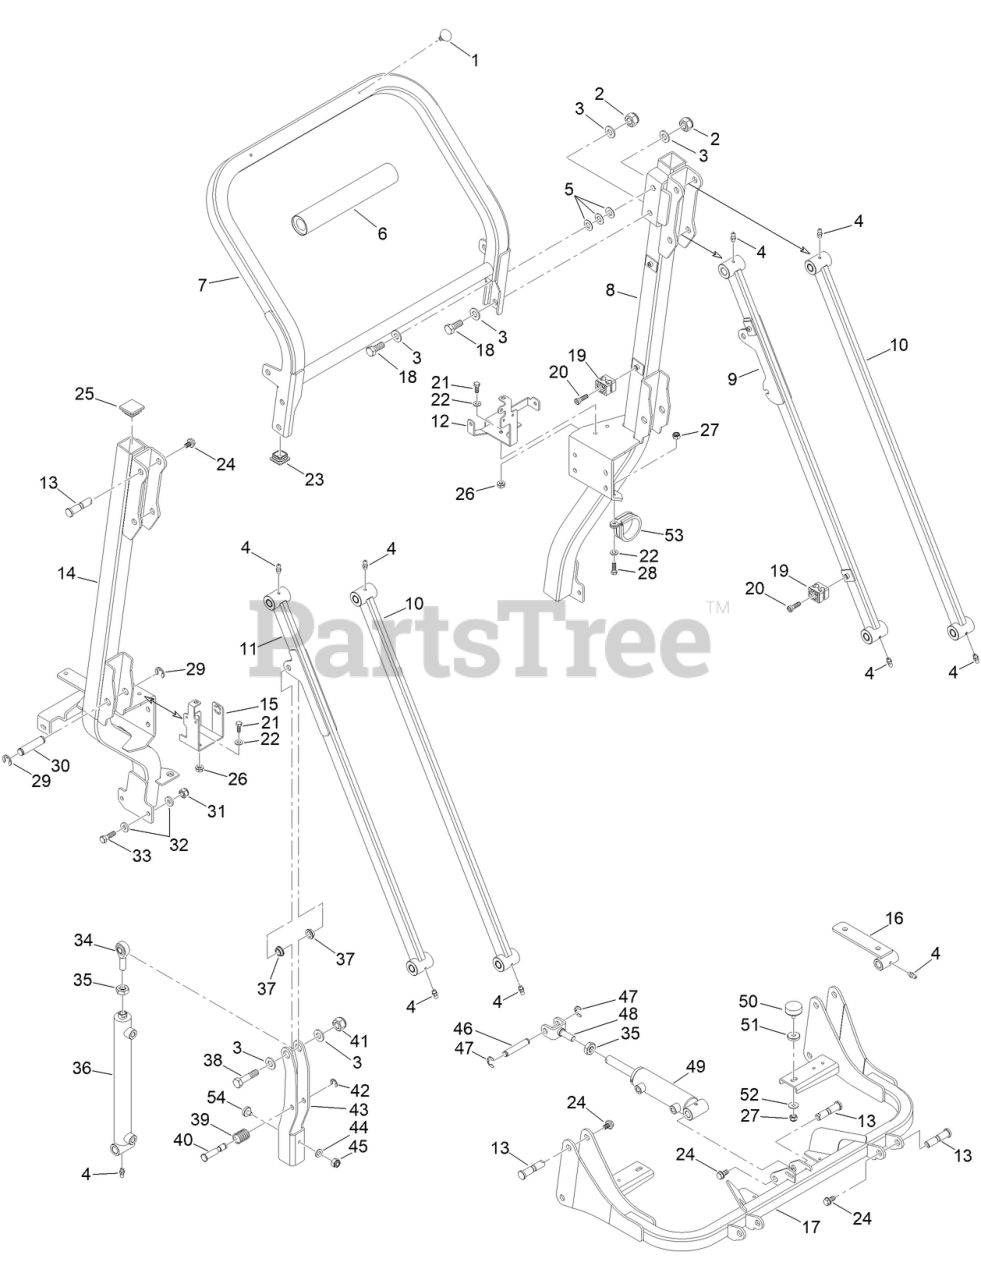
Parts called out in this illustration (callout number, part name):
1	RIVET-PLASTIC
3	WASHER
4	FITTING-GREASE
6	NECK PROTECTION
7	ROLL-BAR
8	PILLAR, LIFTER RH
9	ARM-HOPPER
10	ARM ASSY, UPPER
11	ARM-HOPPER
12	BRACKET, ENGINE RELAYS
13	PIVOT, LIFTER
14	PILLAR, LIFTER LH
15	BRACKET, FAN RELAYS
16	FRAME, HOPPER BODY
17	FRAME, HOPPER ASSY
18	SCREW-HH CAP
19	COLLAR
22	WASHER
29	RING-SNAP
32	WASHER
34	JOINT-BALL
36	CYLINDER
37	BUSHING
39	SPRING
42	RING SNAP
43	ROD-SAFETY
44	WASHER-WAVE
46	PIVOT, HOPPER RAM
47	RING-SNAP
48	FORK, TILTER RAM
49	RAM, DUAL ACTING
50	PAD-RUBBER
51	WASHER
52	WASHER
54	MAGNET
